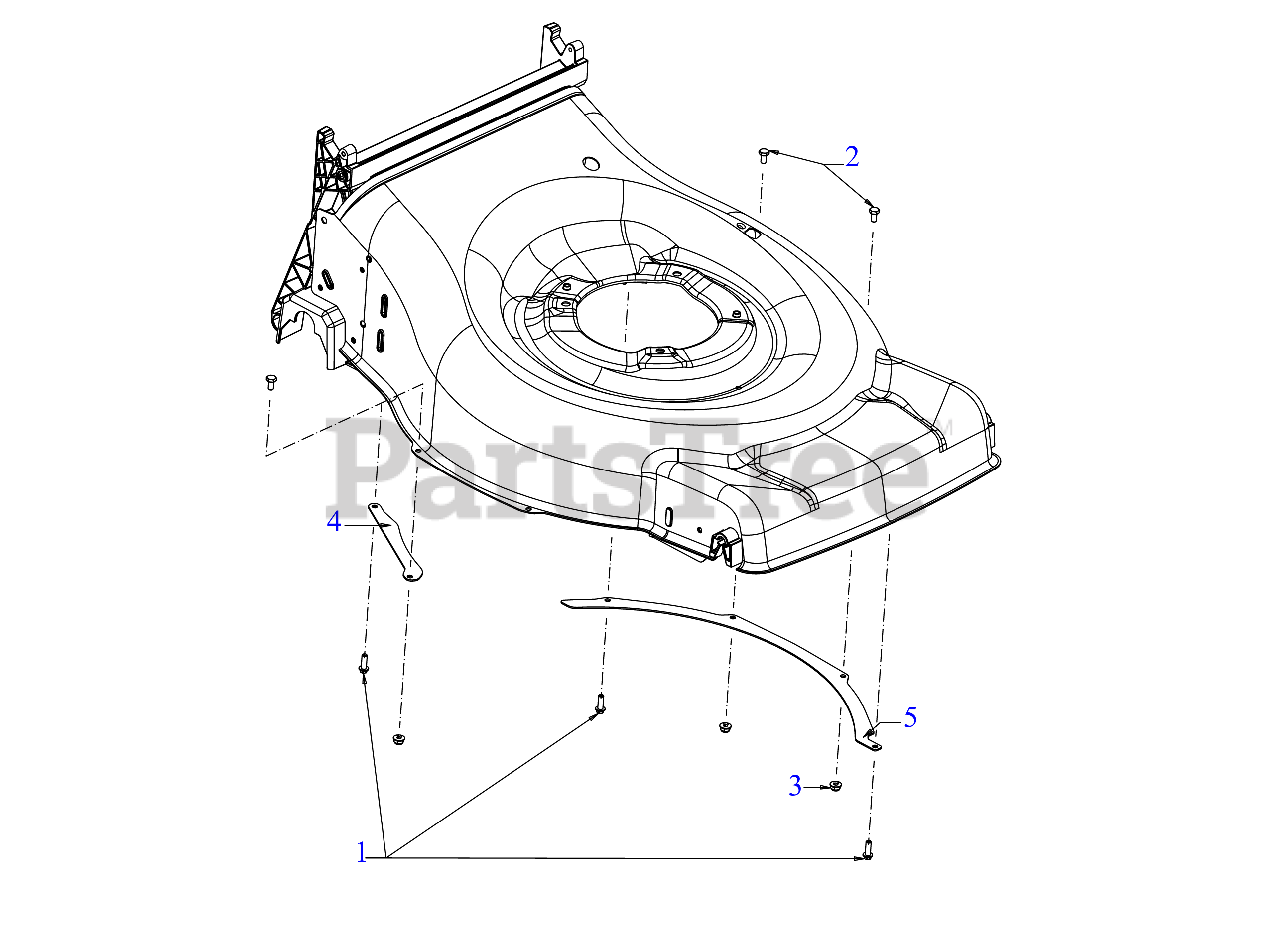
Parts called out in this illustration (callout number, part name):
1	SCREW 1/4 x .750
2	SCREW 1/4-20X.5 GR5
3	FLANGE LOCK NUT
4	23" SUPPORT BRACKET (RH)
5	23" SUPPORT BRACKET (LH)
